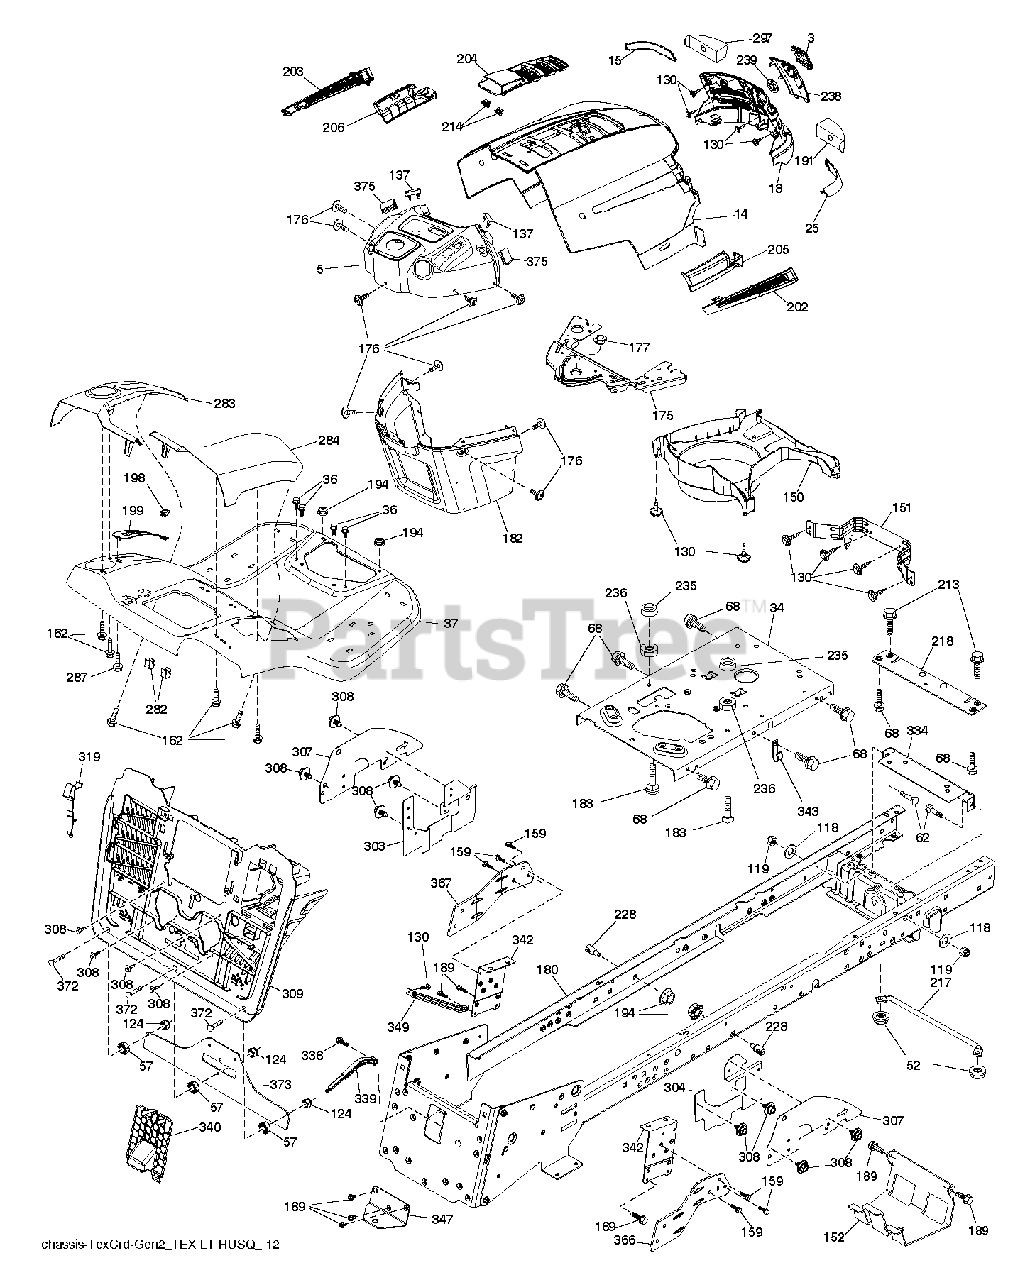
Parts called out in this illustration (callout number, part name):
3	LOGO.HUSQ.GT.LT.CROWN.H
14	HOOD.HUSQVARNA.LT.ORANGE
15	LENS.HUSQVARNA LT.RH
18	GRILLE.SVC.HUSQVARNA.GREY
25	LENS.HUSQVARNA LT.RH
34	PLATE.ENGINE.10GA.CRD.GENII
36	SCREW 5/16"
37	FENDER.TEX.SRD.CRD.FRN.GUARDS
52	LOCKNUT
57	NUT
62	BOLT D
68	SCREW LT
118	WASHER
124	LOCKNUT.NYLOC.1/4-20
130	SCREW.#10 X 0.750.BOS
137	BUMPER DASH
151	BRACKET PIVOT
152	SHIELD.BROWNING.W/TEX
159	SCREW, 3/8-16X3/4
162	SCREW.HI-LO.CONSOLE
175	CROSSMEMBER
176	SCREW.#10-24X5/8.RN.QU
177	BUSHING STEERING
180	WELDMENT.CHASSIS.TEX.CRD.GEN.2
182	DASH.LOWER.PREDATOR LT
183	BOLT.5/16-18X1-1/4 FULL THD
189	SCREW
191	INSERT.REFLECTIVE.RH.
194	NUT LOCK HEX FLANGE 5/16-18
198	INDICATOR.DECK.LIFT.RED
199	PLATE DECK LIFT
202	VENT.SIDE.HUSQVARNA.LT.RT
203	VENT.SIDE.HUSQVARNA.LT.LFT
204	SUBASM.TOP.VENT.HUSQ.LT
205	SKIRT.SIDE.HUSQVARNA.LT.RT
206	SKIRT.SIDE.HUSQVARNA.LT.LEFT
213	BOLT
214	CLIP.RETAINER.TINNER.
217	ROD.PIVOT.HOOD
218	X-PIECE.HOOD.STOP.NON/
228	STUD.FASTNER.W/ANTI-ROTATE
235	SPACER FENDER
236	NUT.CENTERLOCK.5/16-
238	TRIM.HUSQ LT.668
282	CLIP.RETAINER.CONSOLE.LT.HUSQ
283	CONSOLE.DECKLIFT.CRDII.498
284	CONSOLE.PEDAL.HYDRO
287	SCREW 1/4X20
297	INSERT REFLECTIVE
303	SHIELD.LWR.LH.LT.30"CRDSRD.PNT
304	SHIELD.LWR.RH.LT30DECK.PNT.BLK
307	SHIELD.UPPER.CRD.SRD.ISO
308	BOLT, 5/16-18 X 1 3/4
309	BACKPLATE.ASM.TEX.CRD.GEN2.1
319	LEVER.BAG.CRDII.ANTIROTATION
334	BRACKET.ENGINE
338	BOLT BOLT SHOULDER
339	LEVER LEVER BAGGER
340	BATTERY.DOOR.TEX.CRD.GEN.2,1
342	SUPPORT SUPPORT FENDER
343	CLIP CLIP
347	HITCH HITCH TOW TEX CRD GEN 2
349	BRACKET.SUPPORT.LRVB/CRD
366	BRACKET.RH.FRONT.BAGGER.BLACK
367	BRACKET.LH.FRONT.BAGGER.BLACK
372	RHSNB, 1/4-20 X 1, GR5
373	REINFORCEMENT BACKPLATE. CRD B
375	BUMPER CLIP-ON. DASH 1"
